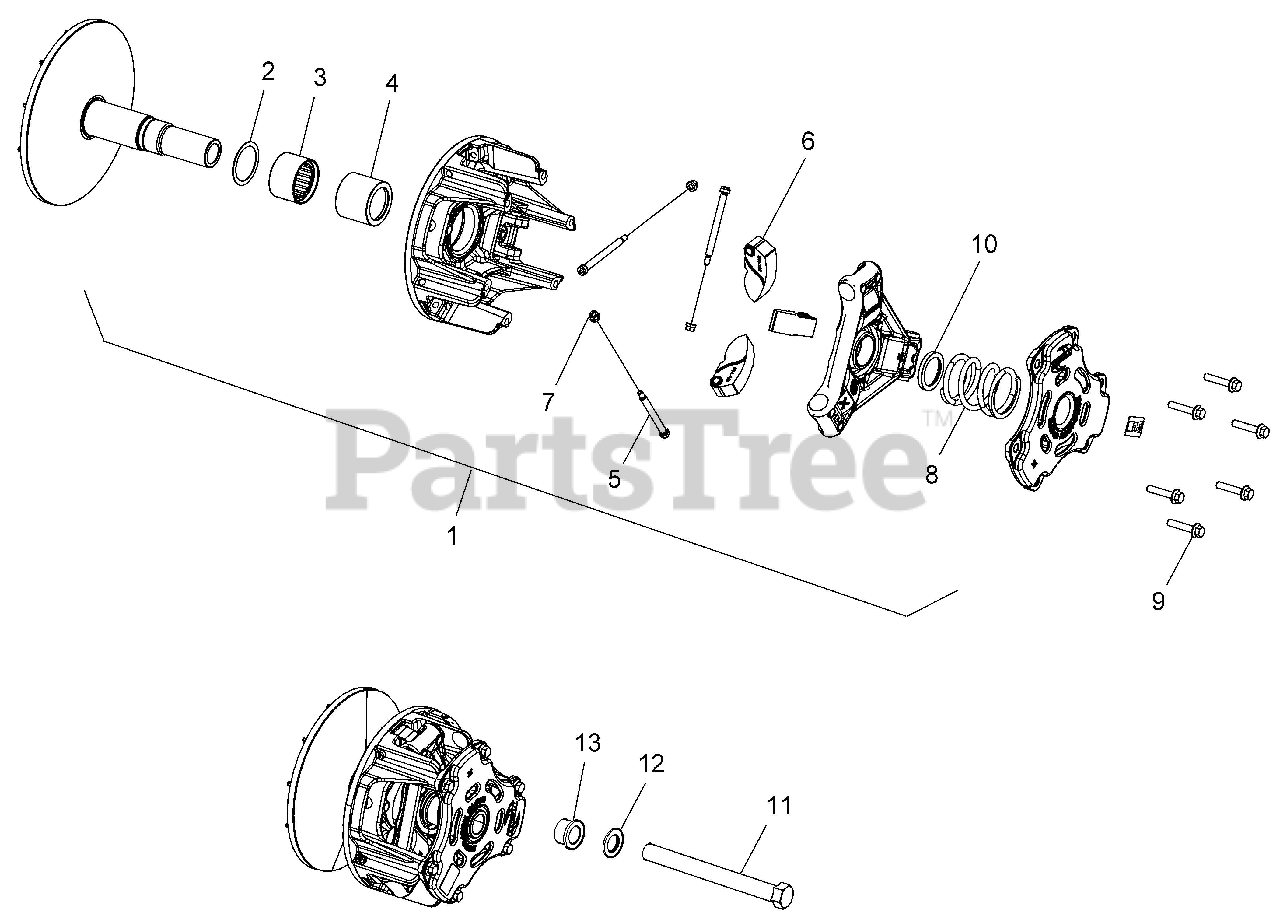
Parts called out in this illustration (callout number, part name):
1	ASM., DRIVE CLUTCH
2	WASHER-THRUST
3	SUBASSY-IDLER SLEEVE PRIMARY
4	CAP, IDLER SLEEVE
5	SCREW, SHOULDER HEX SKT .25 X
6	WEIGHT,CLUTCH,PRIMARY 153G
7	NUT, LOCK HEX #10-24 FLEXLOC
8	SPRING-CLUTCH,75-105
9	SCREW, HEX FLANGE HD 1/4 - 20
10	COLLAR,PRIMARY SHIFT STOP
10	SPACER, CLUTCH
11	SCR-M14X1.5X215, HX, 8.8
13	WASHER,CLUTCH RETAINER
